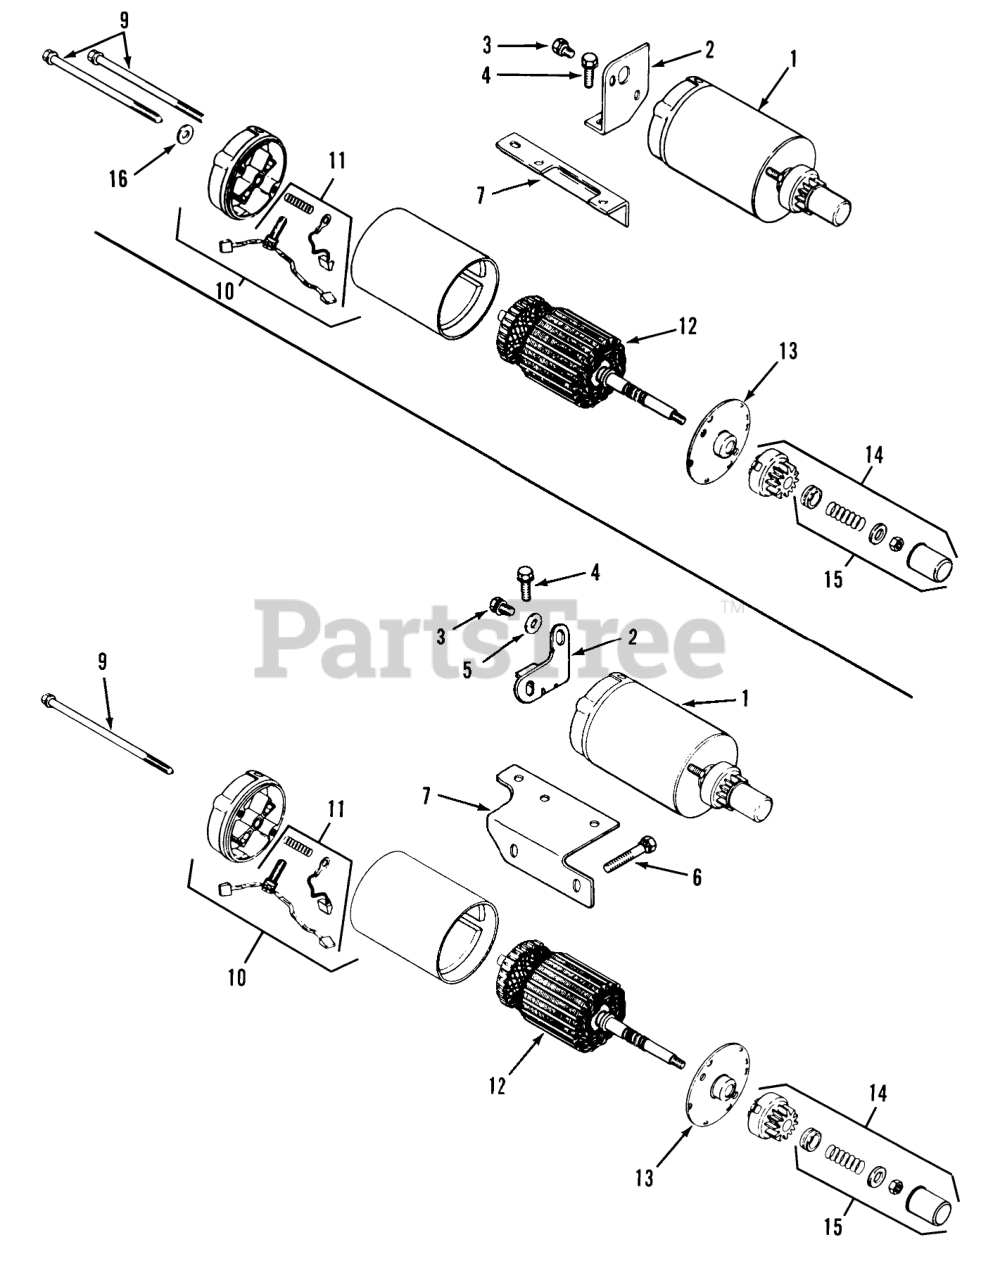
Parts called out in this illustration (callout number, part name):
1	Starter Assembly (Includes Items 9 thru 15)
2	Brace-Starter Tail
3	Screw-Hex. Hd.
4	Screw
6	Screw
7	Bracket-Starter
10	Commutator End Cap Assembly (Includes Item 11)
11	Brush Kit
12	Armature
13	Cap-Drive End
14	Drive Kit (Includes Item 15)
15	Drive Parts Kit
